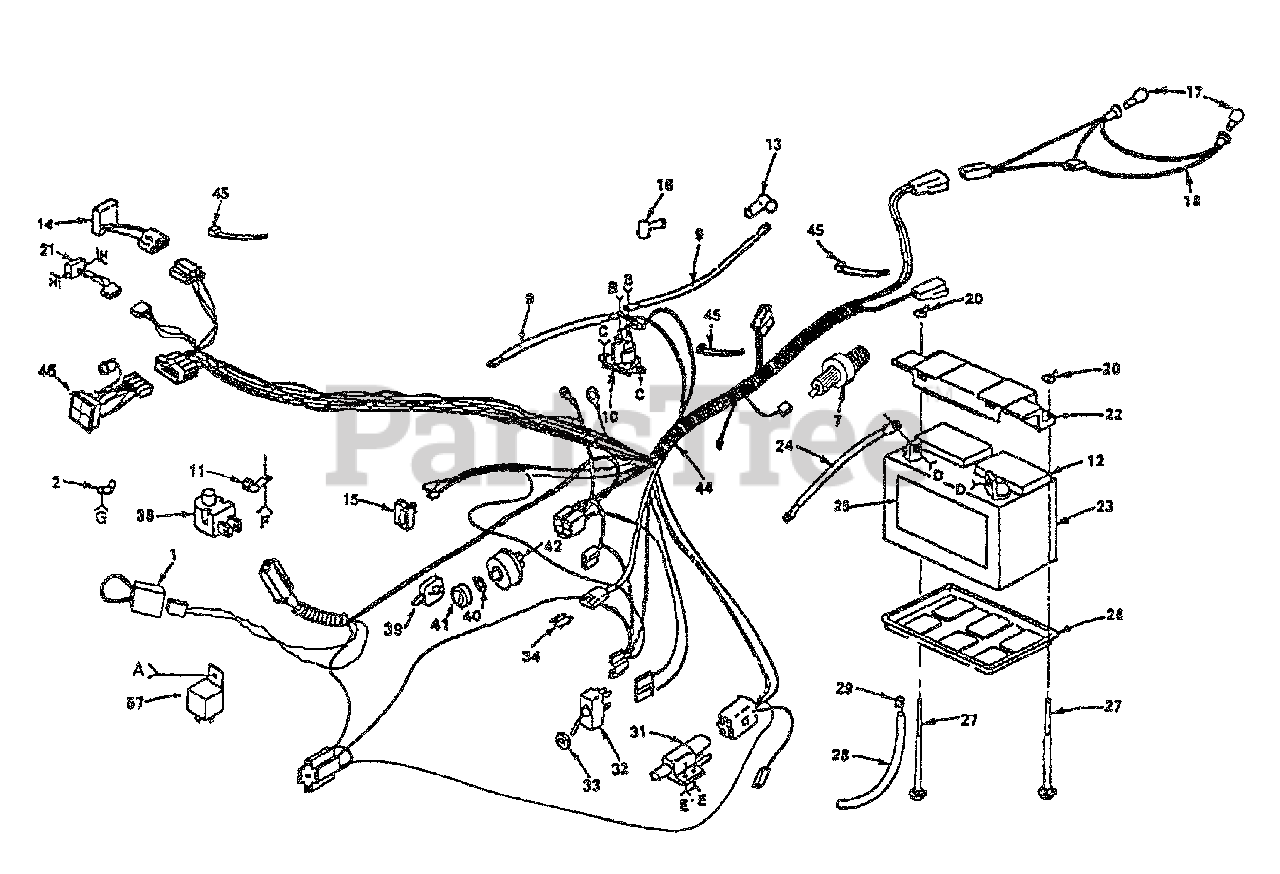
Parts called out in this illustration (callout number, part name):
1	Loop, Wire
2	Clip. Insulated
7	Switch, Oil Sensor
9	Cable - Battery
10	Solenoid
11	Clip - Insulated
12	Battery Caps
13	Clip, Fuel Line
14	Sensor, Low Voltage
15	Switch - Light
16	Cover - Terminal
17	Bulb - Light
18	Harness - Light Socket
20	Nut Wing 1/4 - 20
21	Meter, Hour
22	Guard - Terminal
23	Battery
24	Cable Ground
25	Decal, Battery
26	Tray a Battery
27	Bolt - Carriage 1/4-20 x 7-1/2
28	Tube- Plastic
29	Clamp- Hose
31	Switch- Interlock
32	Switch - P.T.O.
33	Nut - Hex
34	Fuse - 30 Amp
38	Switch, Seat
40	Nut - Ignition
41	Bezel, Ignition
42	Switch - Ignition
44	Harness - Ignition
45	Cable Tie
46	Light Package
57	Assembly - Relay
